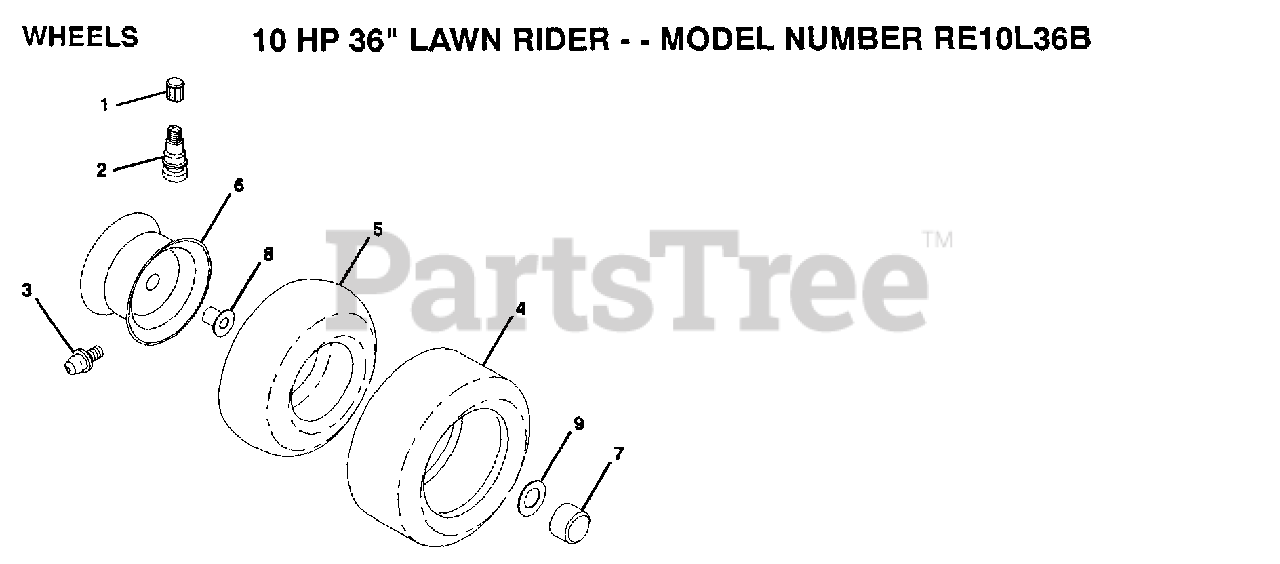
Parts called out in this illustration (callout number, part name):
1	VALVE CAP
2	VALVE STEM LT
3	FITTING LT
5	TUBE.5.3/4.5/6
7	HUB CAP
8	"FLANGE, BEARING"
9	WASHER
